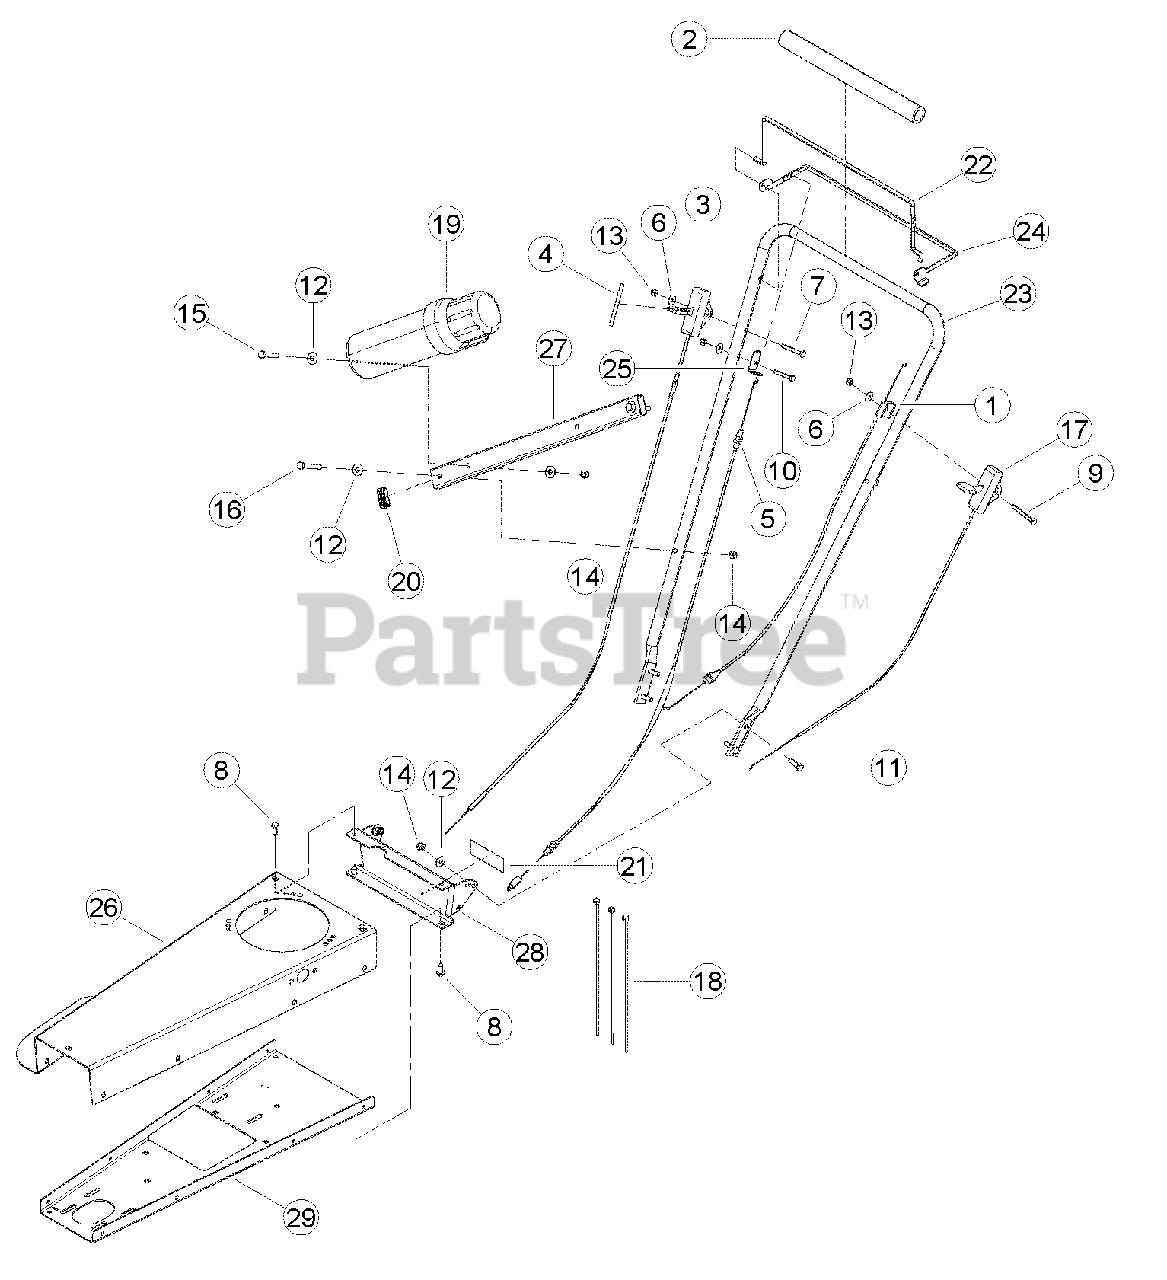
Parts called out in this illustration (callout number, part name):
1	CABLE, BRAKE CONTROL
2	PAD, FOAM HANDLEBAR
3	CABLE, TRANSMISSION CONTROL
4	DECAL, 3 SPEED
5	CABLE, SP CONTROL
6	WASHER, 1/4 FLAT ZP
7	BOLT, 1/4 X 2 HEX HD GR5 ZP (WT160S ONLY)
7	BOLT, 1/4 X 1-3/4 HHCS GR5 ZP (WT190S ONLY)
8	SCREW, 11/32 X 7/8 HWH AB THREAD ZP
9	BOLT, 1/4 X 2-1/4 HCS GR5 ZP (WT160S ONLY)
9	BOLT, 1/4 X 1-1/2 HHCS GR5 ZP (WT190S ONLY)
10	BOLT, 1/4 X 1-1/4 HEX HD GR5 ZP
11	BOLT, 5/16 X 1 HEX HD GR5 NC ZP
12	WASHER, 5/16 FLAT ZP
13	NUT, 1/4 NE NYLOCK ZP
14	NUT, 5/16 NE NYLOCK ZP
15	BOLT 5/16-18 X 1-3/4 HCS GR5 ZP
16	BOLT, 5/16 X 2-1/4 HCPS GR5
17	THROTTLE CONTROL (WT160S ONLY)
18	STRAP, 11 IN. BLACK TIE
19	CONTAINER, MANUAL
20	CAP, PLASTIC 3/4 X 1-1/2 TUBE
21	DECAL, ATLANTIC BRIDGE LTD INFO (WT190S ONLY)
22	BAIL, TRIMMER
23	HANDLEBAR, TRIMMER
24	WELDMENT, SP BAIL
25	ANCHOR, SP CABLE
26	BODY, TRIMMER
27	TUBE, CONTAINER MANUAL
28	CHANNEL, HANDLE SUPPORT
29	BOTTOM, TRIMMER FRAME
